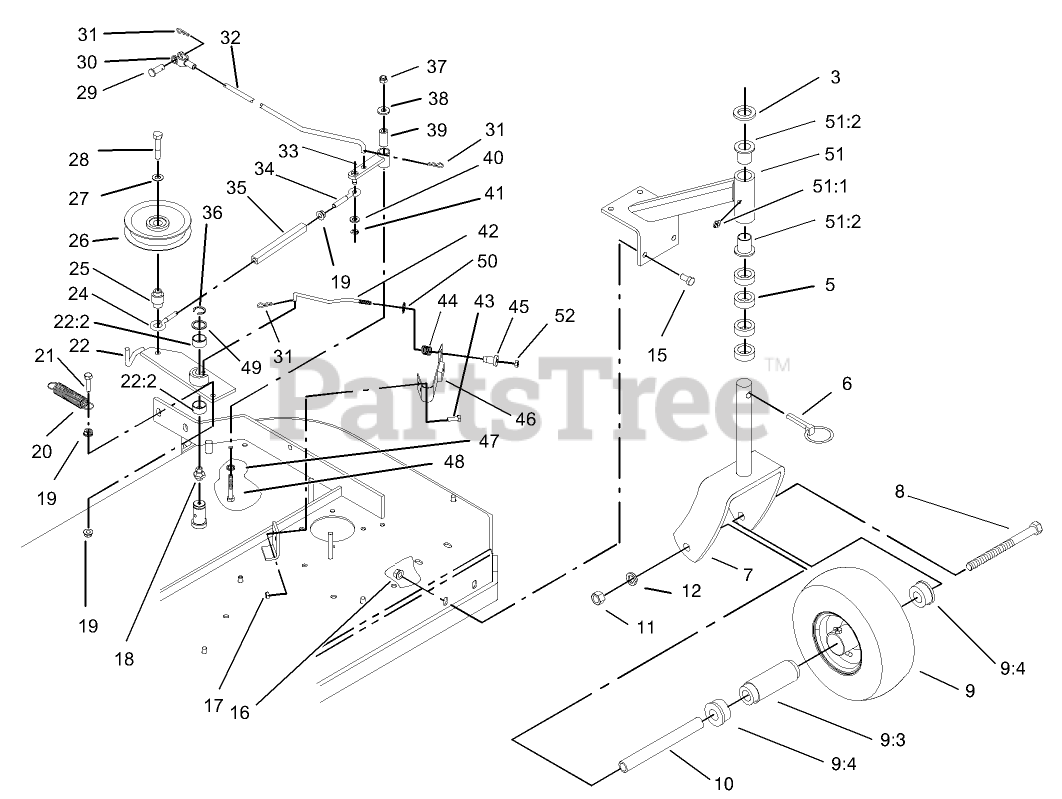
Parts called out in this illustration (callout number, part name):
3	WASHER-FLAT
5	SPACER-CASTER
7	FORK
8	SCREW-HH
9	WHEEL AND TIRE ASM
9:3	BEARING
9:4	BUSHING
10	SPACER
11	NUT-HH
12	WASHER-LOCK
15	SCREW-HH
16	NUT-HHF, WHIZ
17	NUT-LOCK, NI
18	FITTING-GREASE
19	NUT-HF
20	SPRING-EXTENSION
21	SCREW-HH
22	Idler Arm ASM
22:2	SLEEVE-BEARING
24	EYEBOLT-THREAD, LH
25	BUSHING-ENGAGEMENT
26	PULLEY-IDLER
27	WASHER-BELLEVILLE
28	SCREW-HH
29	PIN-CLEVIS
30	YOKE-ADJUSTABLE
31	PIN-COTTER
32	ARM-ASSIST, LINKAGE
33	ARM-ASSIST
34	EYEBOLT-THREAD, RH
35	BODY-TURNBUCKLE
36	RING-RETAINING, EXT
37	NUT-LOCK, NI
38	WASHER-FLAT
39	TUBE-PIVOT
40	WASHER-PLAIN
41	RING-RETAINING, EXT
42	ROD-BRAKE
43	SCREW-HH
44	SPRING-COMPRESSION
45	SPACER-FLANGED
46	PAD AND SPRING ASM
47	WASHER-SPRING
48	SCREW-HH
49	WASHER-SPINDLE
50	RING-PUSH ON
51	SUPPORT ASM
51:1	FITTING-GREASE
51:2	BEARING-FLANGED
52	NUT-LOCK, NI
